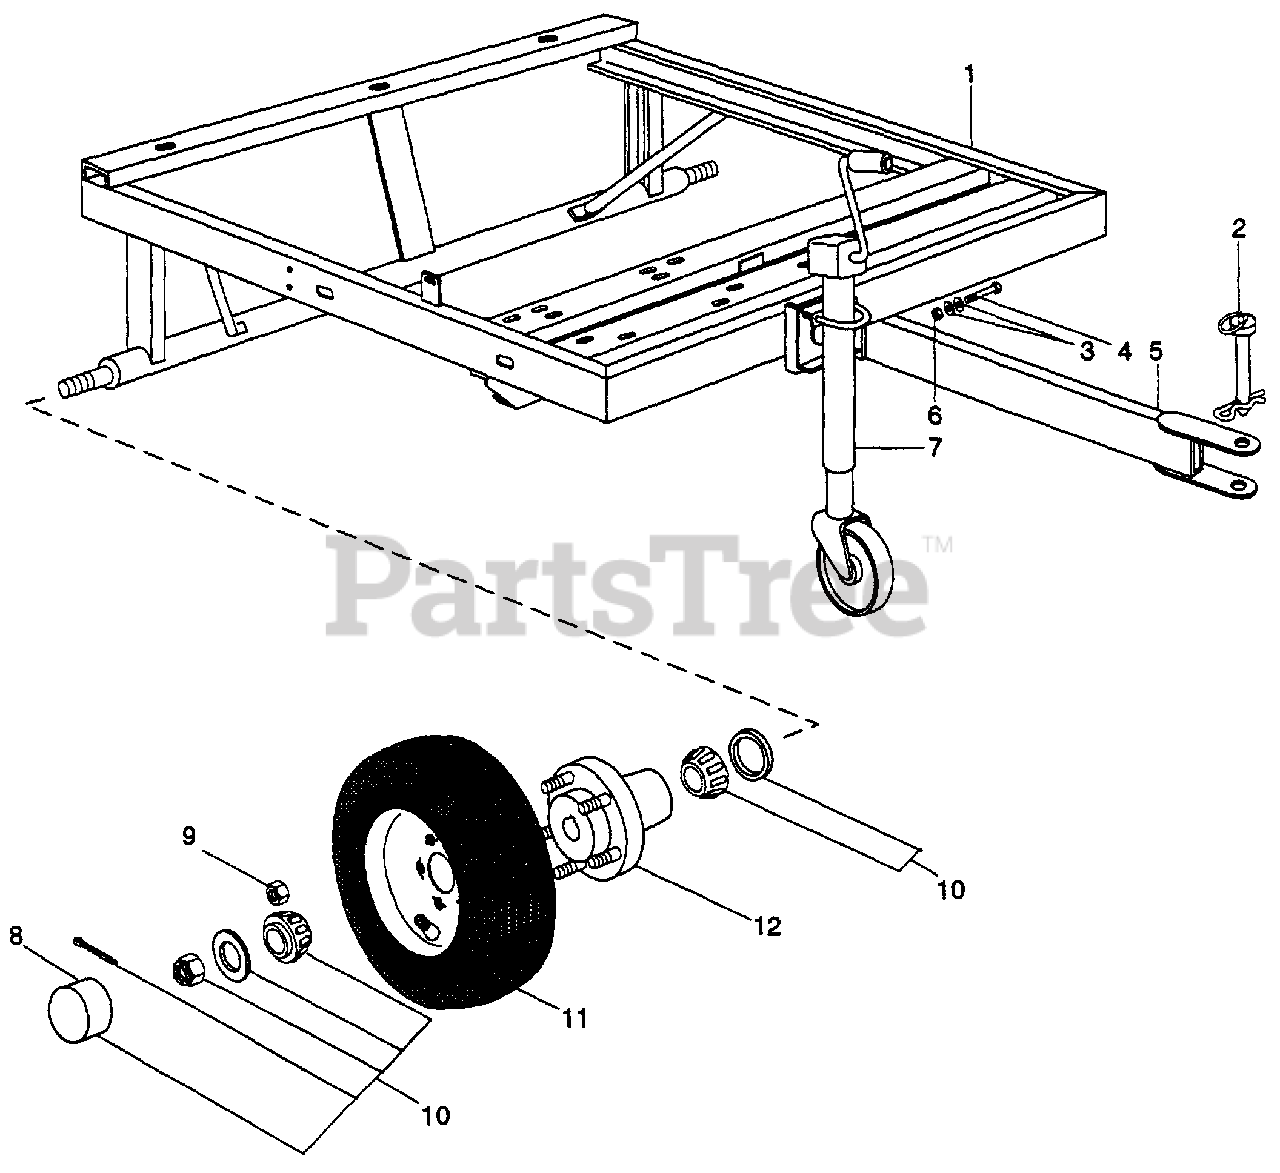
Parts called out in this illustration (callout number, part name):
1	FRAME WELDMENT
2	HITCH PIN 1 INCH
3	WSHR-FL-STL .641 X 1.125 X .188
4	BLT-HEX .62-11 X 3.00 PL GR 5
5	TONGUE WELDMENT
6	NUT-LK-TOP .62-11 PL
8	DUST CAP
9	KIT, WHEEL NUT
10	KIT, HUB COMPLETE 1050 VAC
11	TIRE & WHEEL ASSEMBLY
12	HUB ASSEMBLY
